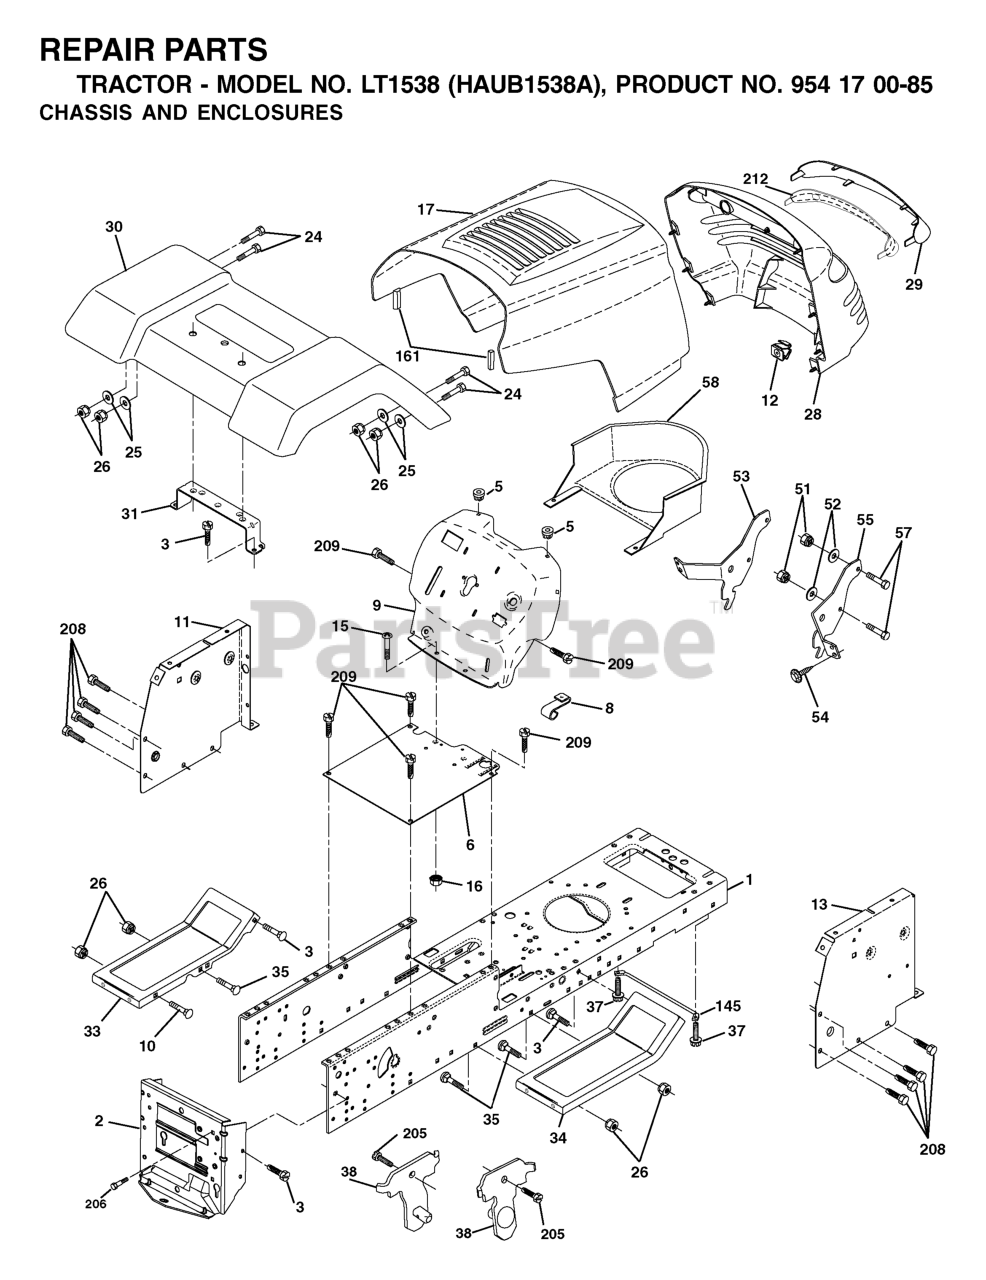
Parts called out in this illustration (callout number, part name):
2	DRAWBAR, 12GA
3	SCREW 3/8-16X3/4
5	BUMPER.RUBBER.HOOD
6	SADDLE FLAT
8	CLIP RETAINER
10	BOLT D
11	PANEL.DASH.LH.LTX
13	PANEL DASH RH
15	Screw, Machine, Truss Head 5/16-18 UNC x 3/4
16	NUT
17	HOOD ASM.
25	WASHER
26	NUT
28	GRILL ASSEMBLY
29	LENS P/L
30	FENDER
31	BRACKET FENDER
33	FOOTREST PNT LH
34	FOOTREST PNT RH
37	Screw 5/16-18 x 1/2 Hex, Self Tapping 5/16-18 x 1/2
38	BRACKET.ASM.PIVOT.MOWER.REAR
51	LOCKNUT.NYLOC.1/4-20
53	BRACKET.GRILLE.LH
54	SCREW.HEX.WS.HD.8-18 X 7/8
57	BOLT
58	AIR DUCT P/L/LT
145	ROD PIVOT CHASSIS/HOOD
161	EXTRUSION BUMPER (3 2) (2 2)
206	SHOULDER BOLT 5/16-18TT
208	SCREW 3/8-16X1/2
209	SCREW, 3/8-16X3/4
212	REPL BY 532 1745-03
